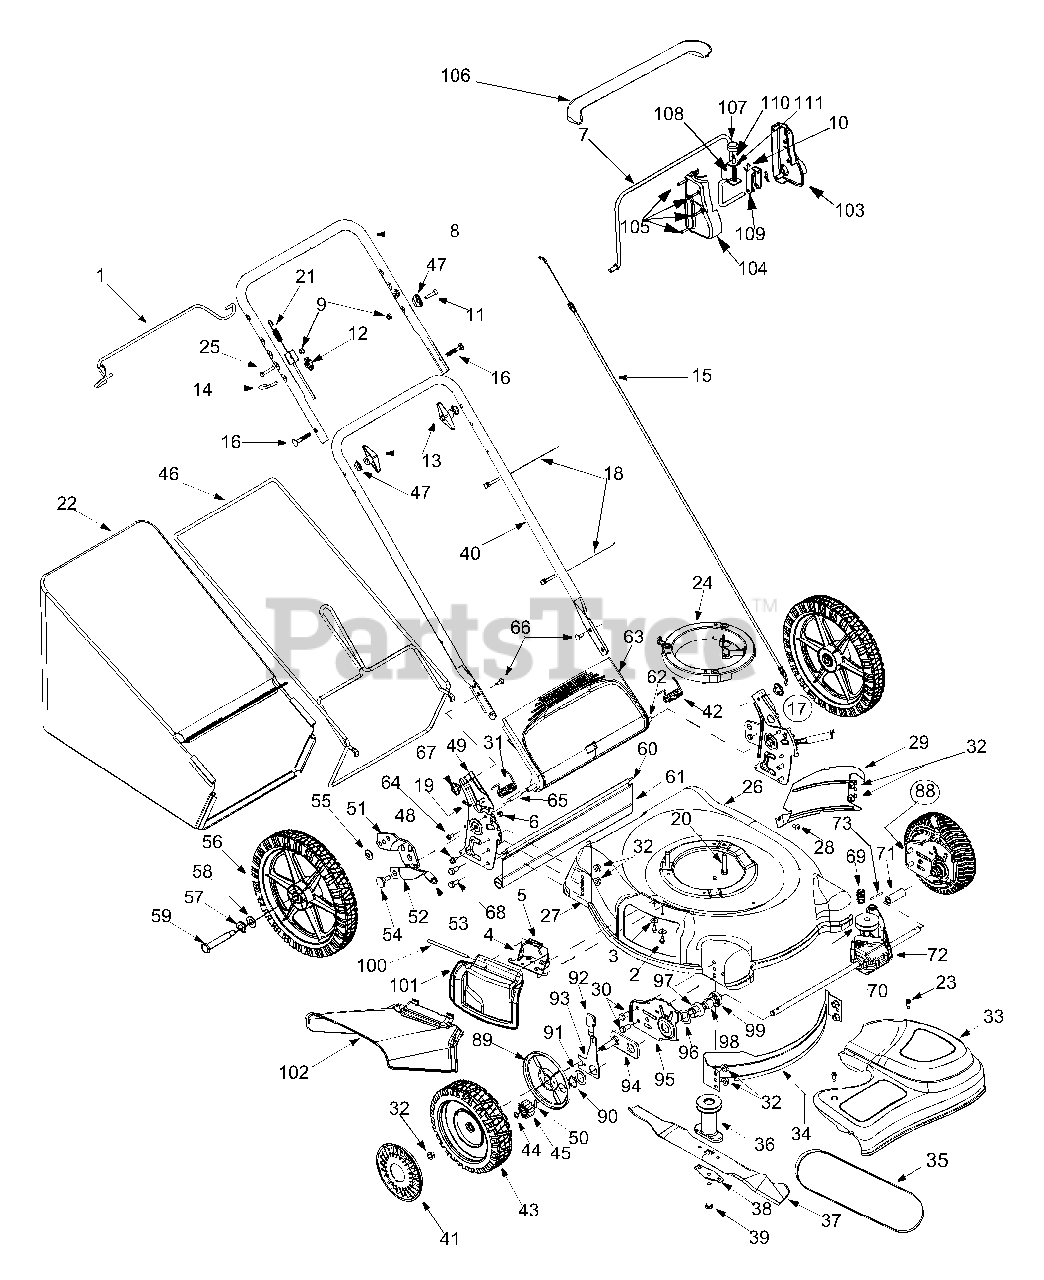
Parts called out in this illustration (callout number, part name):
2	TT Screw 1/4-20 x 0.5
3	Bell Washer.265 x 0.75
4	Chute Deflector Adapter
5	Torsion Spring
6	Lock Nut
10	Torsion Spring
11	Hex Hd. Cap Screw
12	Handle Knob
13	Handle Knob
14	Eye Bolt
15	Control Cable
16	Carriage Bolt 5/16-18 x 2.0
17	LH Bracket Assembly
18	Cable Tie
19	Cotter Pin
20	Self-Tapping Sems Screw
21	Drive Cable
22	Grassbag Assembly
23	Shoulder Screw # 12 -24
24	Engine Spacer
25	Hex Bolt 1/4-20 x 1.5
26	21" Deck
28	Screw AB: 1/4-14:.625
30	Hex Screw 3/8-16 x.75
31	Torsion Spring - R.H.
32	Hex Nut 3/8-16
33	Transmission Cover (Yellow)
36	Blade Adapter w/ Pulley
37	21" Mulching Blade
38	Blade Bell Support
39	Hex Screw 3/8-24 x 2.50
41	Hub Cap
42	Torsion Spring - L.H.
43	Wheel 8 x 2.125
44	Snap Ring
45	Gear 14T RH FWD
47	Saddle Washer
48	Hex Scr. w/Washer 1/4-14 x.625
49	RH Handle Bracket
50	Dowel Pin
51	RH Pivot Bar
52	Height Adj. Lever
53	Foam Grip
54	Shoulder Scr.500 Dia. x.434
55	Washer.401 x.870 x.063
56	Wheel 14 x 2.125
57	Spring Washer.50 I.D. x 1.0 O.D.
58	Flat Washer
59	Shoulder Screw
60	Wire
61	Rear Trailing Shield
62	Pivot Rod
63	Rear Discharge Door
64	Machine Screw
65	Spacer.375 x.50 x 1.02" Lg.
66	Carriage Bolt 1/4-20
67	Wing Nut
68	Hex Bolt 3/8-16 x 1.0"
69	Belt Tension Spring
70	Input Pulley
71	Slev. Spacer LH
72	Transmission Assembly
73	Roll Pin
88	Height Adjustment Assembly LH
89	Wheel Dust Cap
90	Snap Ring
91	Washer
92	Adjustment Knob
93	Front Lever Assy. RH
94	Pivot Plate Assembly
97	Bearing Support
98	Bearing Sleeve
99	Bearing Retainer
100	Hinge Pin
101	Mulch Plug Complete
102	Chute Deflector
103	Control Lever LH
104	Control Lever RH
105	Hi-Low Screw
106	Bail Cover
107	Button
108	Compression Spring
109	Lever
111	Retention Ring
